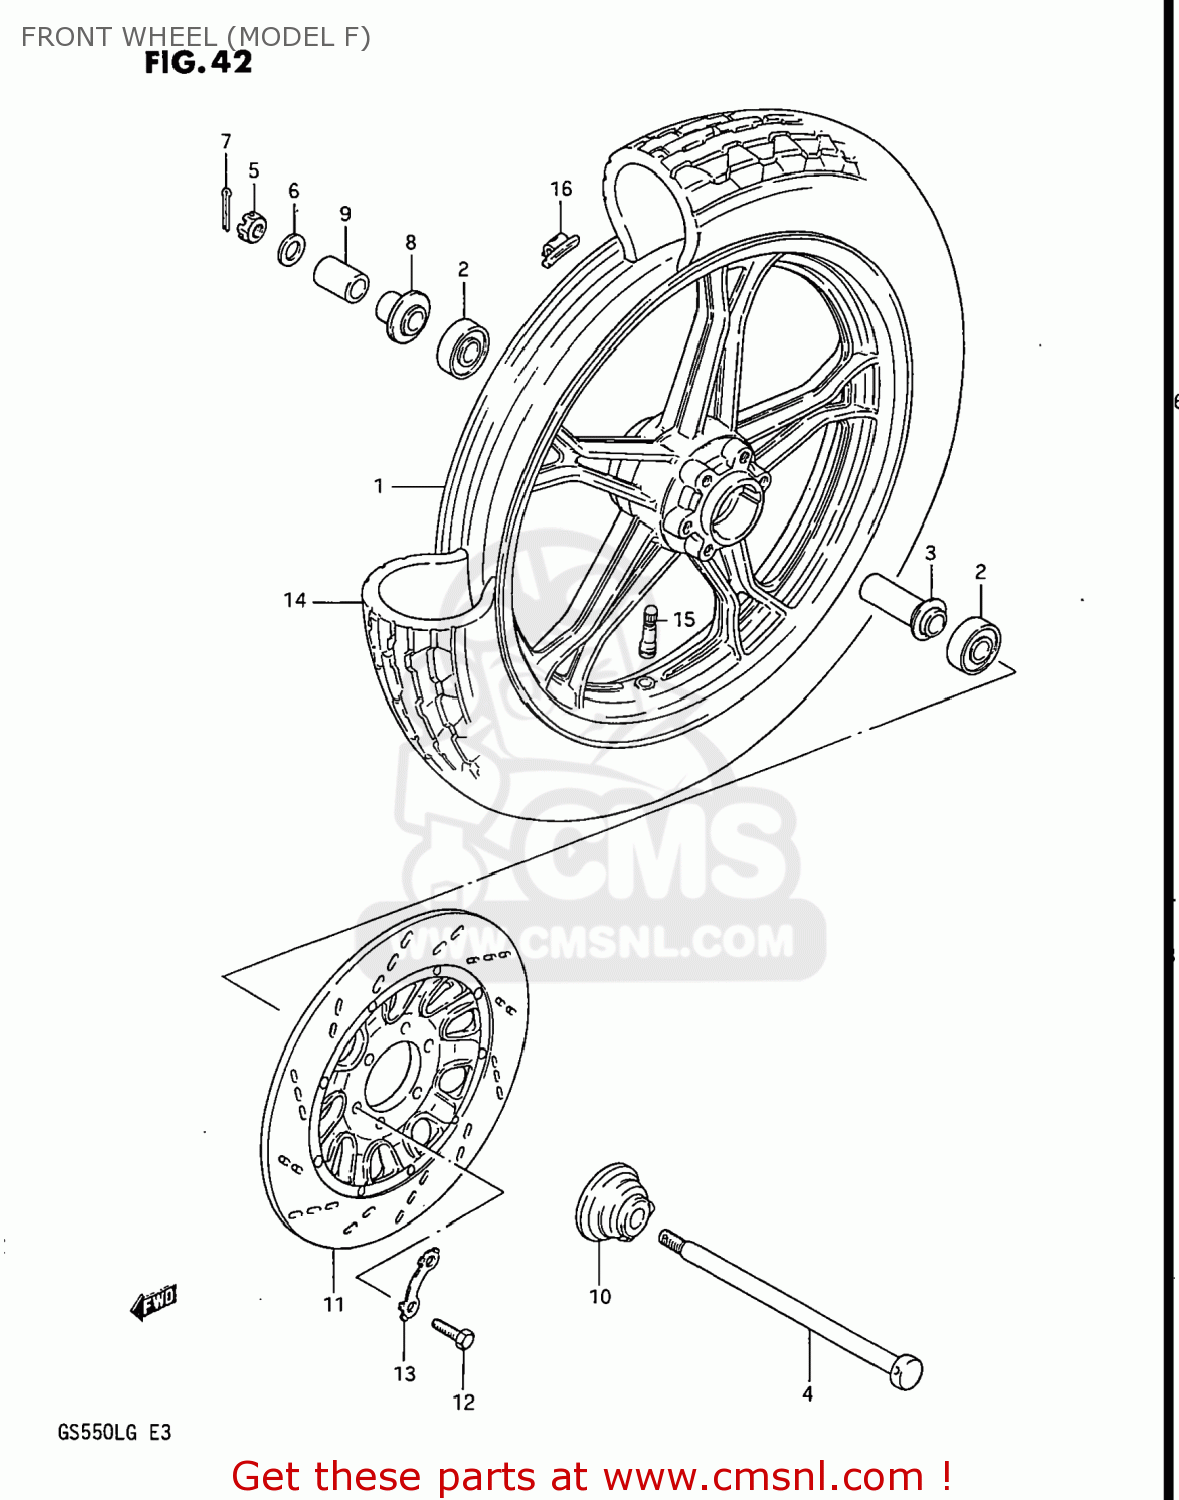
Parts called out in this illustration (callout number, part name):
1	WHEEL, FRONT (2.15X16)
2	BEARING
3	SPACER,FRONT HUB BEARING
4	AXLE,FR
5	NUT 12MM
6	WASHER
7	COTTER PIN
8	SPACER,FR HUB BEARING,R
9	SPACER (15X22X32.5)
10	BOX ASSEMBLY,SPEEDOMETER GEAR
11	DISC,BRAKE
12	BOLT(8X30)
13	WASHER
14	TIRE,FRONT
15	VALVE,TIRE
16	BALANCER,WHEEL
